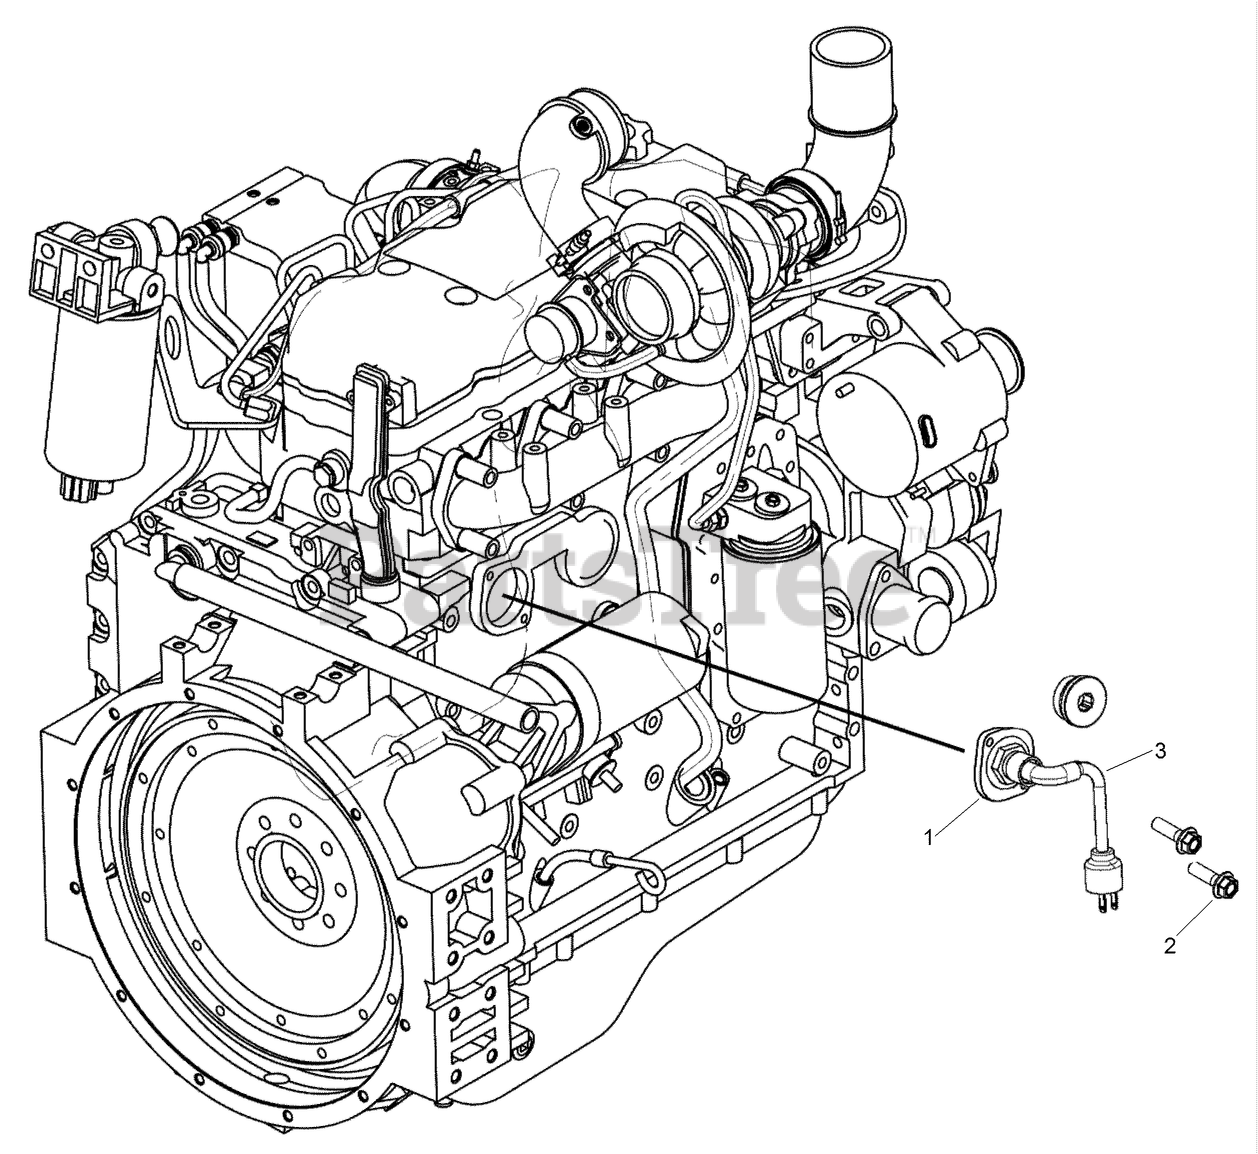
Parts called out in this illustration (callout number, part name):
1	HEATER-COOLANT/BLOCK, 12V
2	SCREW, METRIC FLANGE FULL-M8 x 16
3	CORD - Coolant Heater
